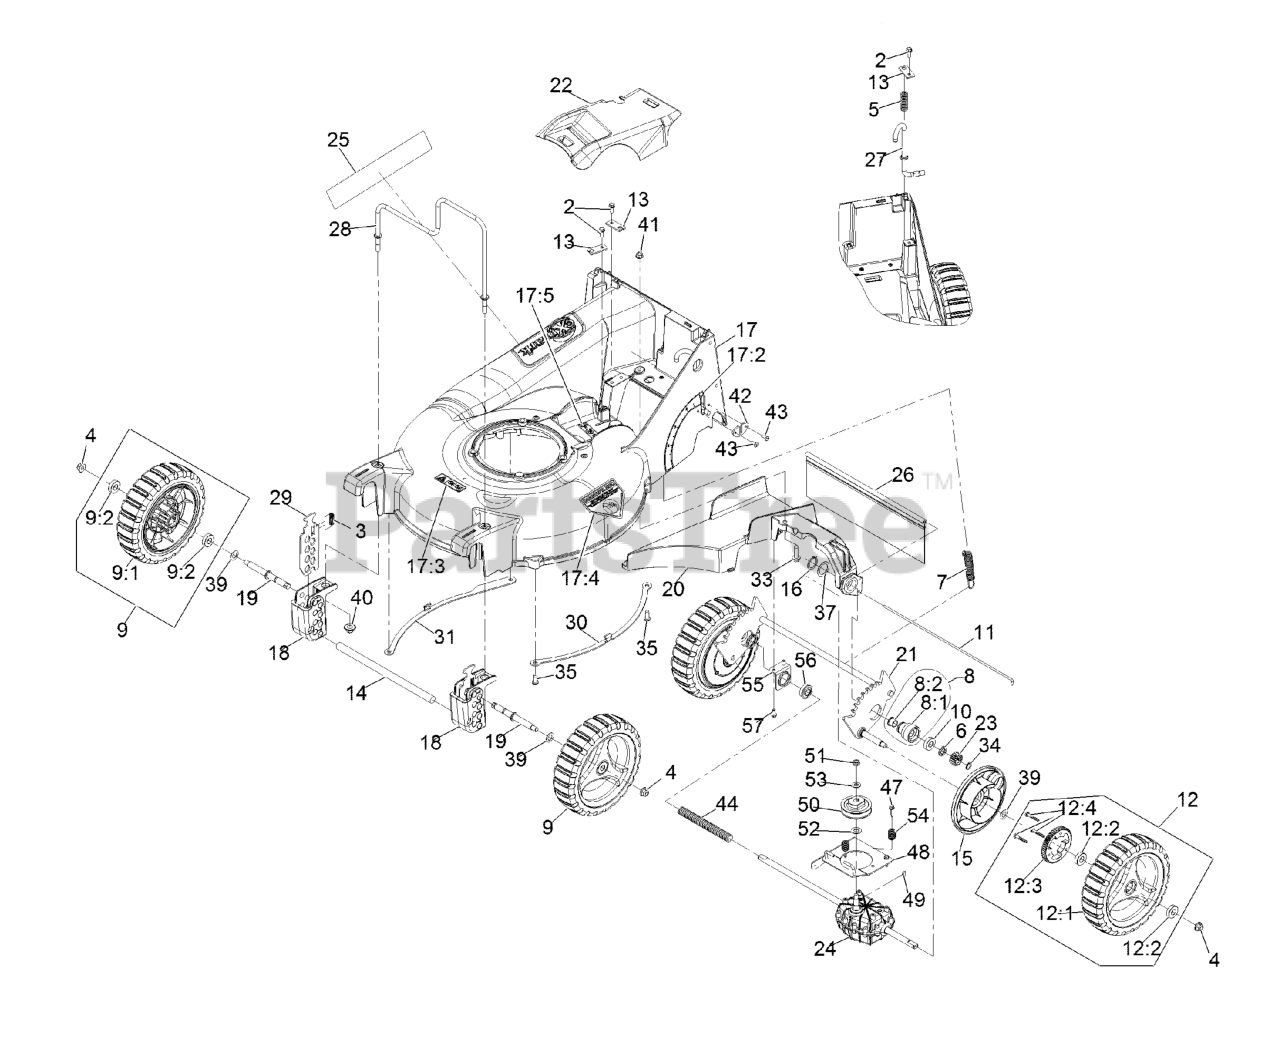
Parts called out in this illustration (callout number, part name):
2	SCREW-HWH
3	SPRING-COMPRESSION
4	NUT-HF, NI
5	SPRING-COMPRESSION
6	SPACER-BUSHING
7	SPRING-EXTENSION
8	HOUSING ASM
8:1	HOUSING-BEARING
8:2	BEARING-FLANGE
9	WHEEL ASM, 9" W/BEARINGS
9:1	WHEEL ASM, 9"
9:2	BEARING-BALL
10	BEARING-BALL
11	ROD,SHIELD
12	WHEEL ASM, 9 W/GEAR
12:1	WHEEL ASM, 9"
12:2	BEARING-BALL
12:3	GEAR-WHEEL, 52T
12:4	STUD-DRIVE
13	BRACKET,MOUNT
14	ROD,BUMPER
15	COVER,GEAR
16	RING-RETAINING
17	DECK W/DECALS
17:2	DECAL-HEIGHT OF CUT
17:3	DECAL-WARNING, BLADE
17:4	DECAL-DANGER
17:5	DECAL-DANGER
18	BLOCK,FRONT QUADRANT
19	AXLE-WHEEL
20	BRACKET-TRANSMISSION AND
21	WLD,REAR AXLE P21
22	COVER,BELT
23	GEAR-PINION, 15T
24	TRANSMISSION-HD, 4.5/1
25	DECAL-COMM 21 X-SERIES
26	SHIELD-TRAILING P21
27	ROD-HEIGHT ADJ P21
28	GUARD,ENGINE
29	PLATE, FRONT HEIGHT
33	SCREW-HWHTF
34	RING-RETAINING
35	SCREW-BHTF
39	WASHER-PLAIN
40	Nut-Nyloc 3/8-16 Flg
41	NUT-HF, NI
42	PLATE,WEAR
43	RIVET-BLIND
44	COVER-SHAFT-DRIVE
47	SCREW-SPECIAL
48	TRANSMISSION PLATE ASM
49	KEY-WOODRUFF
51	NUT-HEX
52	WASHER-THRUST
53	WASHER-FLAT
54	SPRING,COMPRESSION
55	MOUNT-BEARING
56	BEARING-BALL
57	SCREW-HWH
